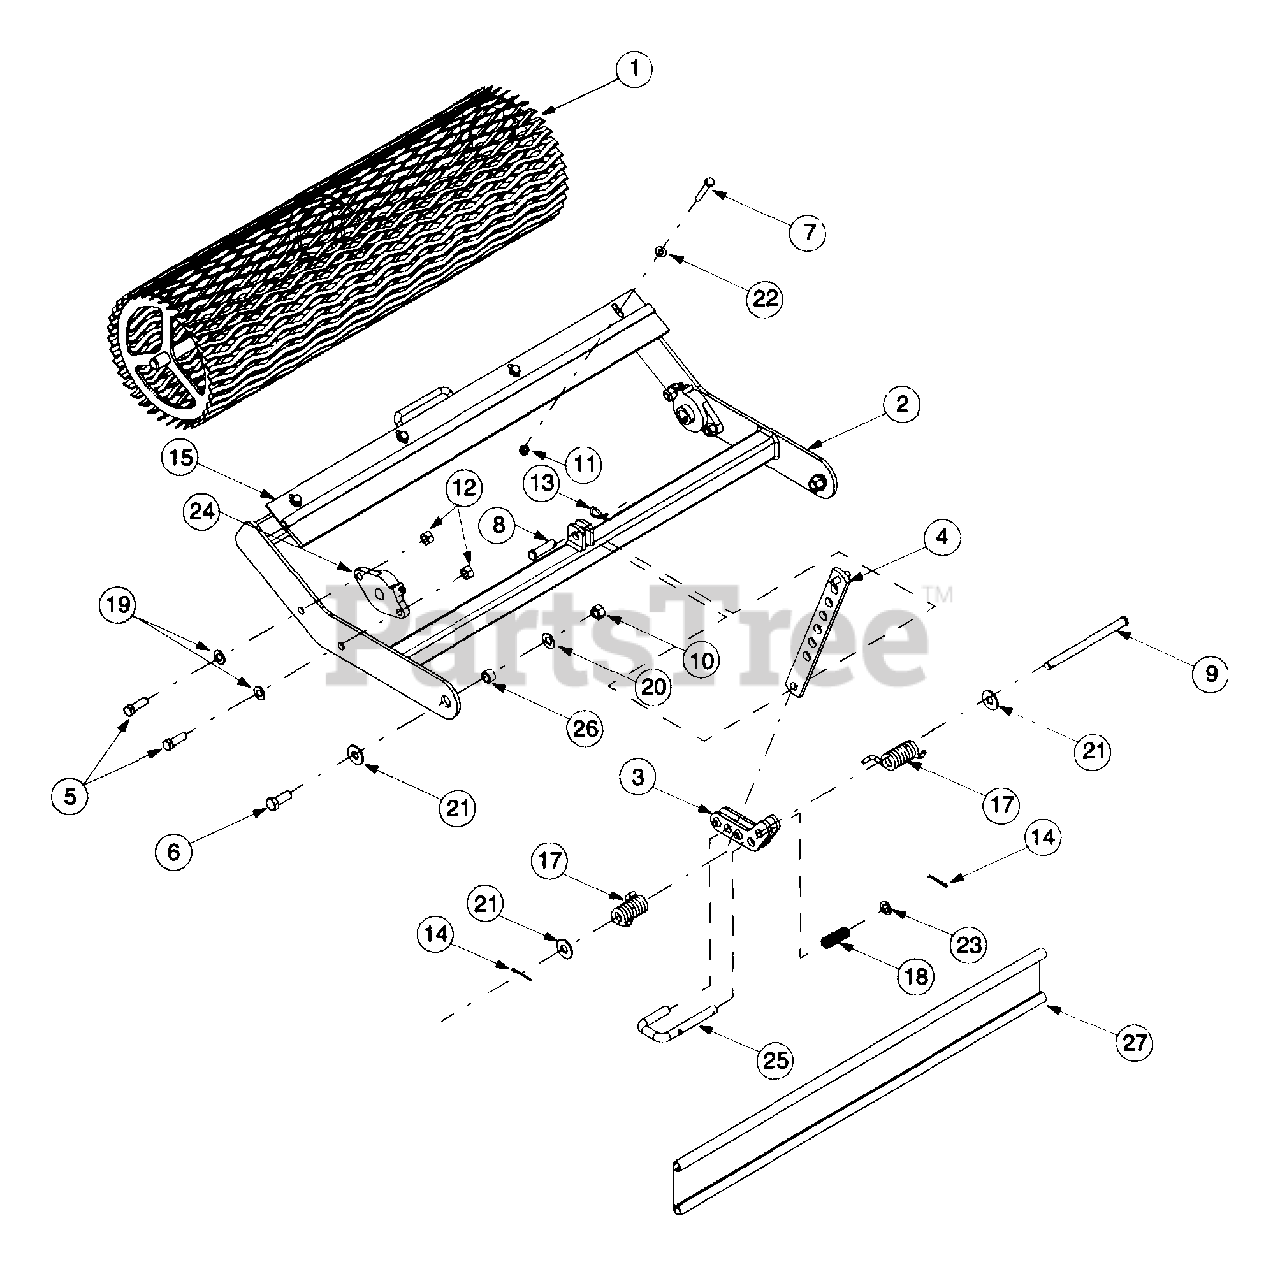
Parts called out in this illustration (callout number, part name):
1	42-inch Roller Assembly
2	Roller Frame Assembly
3	Roller Bracket Assembly
4	Adjustment Bar
5	Hex Cap Screw, 7/16-20 x 1.25
6	Hex Cap Screw, 1/2-13 x 1.25
7	Hex Cap Screw, 5/16-18 x 2.0
8	Clevis Pin, .50 x 1.59
9	Clevis Pin, .50 x 6.5
10	Hex Nut, 1/2-13
11	Hex Lock Nut, 5/16-18
12	Hex Lock Nut, 7/16-20
13	Internal Cotter Pin
14	Cotter Pin 1/8 x 1.25
15	42-inch Roller Brush
17	LH Torsion Spring
18	Compression Spring, .57 x 2.09
19	Flat Washer, .474 x .879 x .064
20	Belleville Washer
21	Flat Washer, .536 x 1.262 x .101
22	Flat Washer, .344 x .688 x .065
23	Flat Washer, .50 x .875 x .060
24	Flange Bearing, .75
25	Roller Locking Rod
26	Spacer, .51 x .75 x .44
